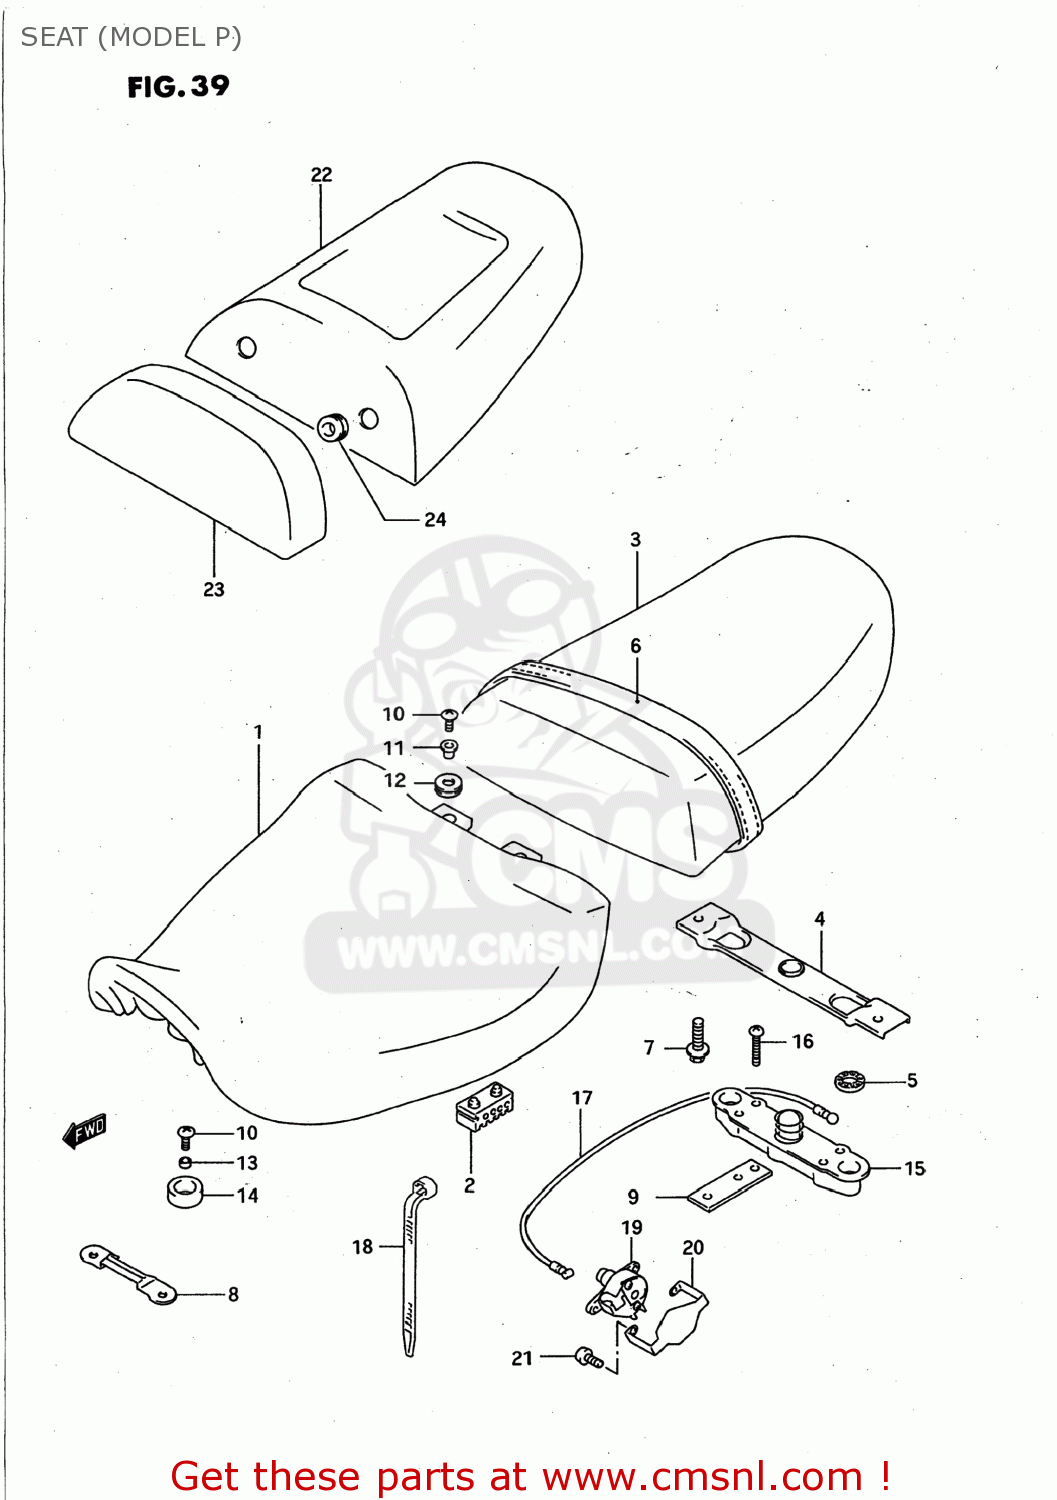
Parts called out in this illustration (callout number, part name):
1	SEAT ASSY
2	CUSHION,SEAT(40X20X15)
3	SEAT ASSEMBLY,PILLION
4	STRIKER,SEAT LOCK
5	CUSHION
6	BAND,SEAT
7	BOLT
8	PLATE,SEAT FR HOOK
9	BRACKET COMP,SEAT SUPPORT
10	SCREW
11	WASHER
12	CUSHION
13	SPACER (6.8X10X4.7)
14	CUSHION,TAIL COVER UPR
15	LOCK ASSY,SEAT STRIKER
16	SCREW
17	CABLE,SEAT LOCK
18	CLAMP L:165
19	LOCK SET,SEAT
20	PLATE,SEAT LOCK GUARD
21	SCREW(6X12)
22	BOX SET,SEAT TAIL
23	BACKREST COMP,SEAT
24	CUSHION
